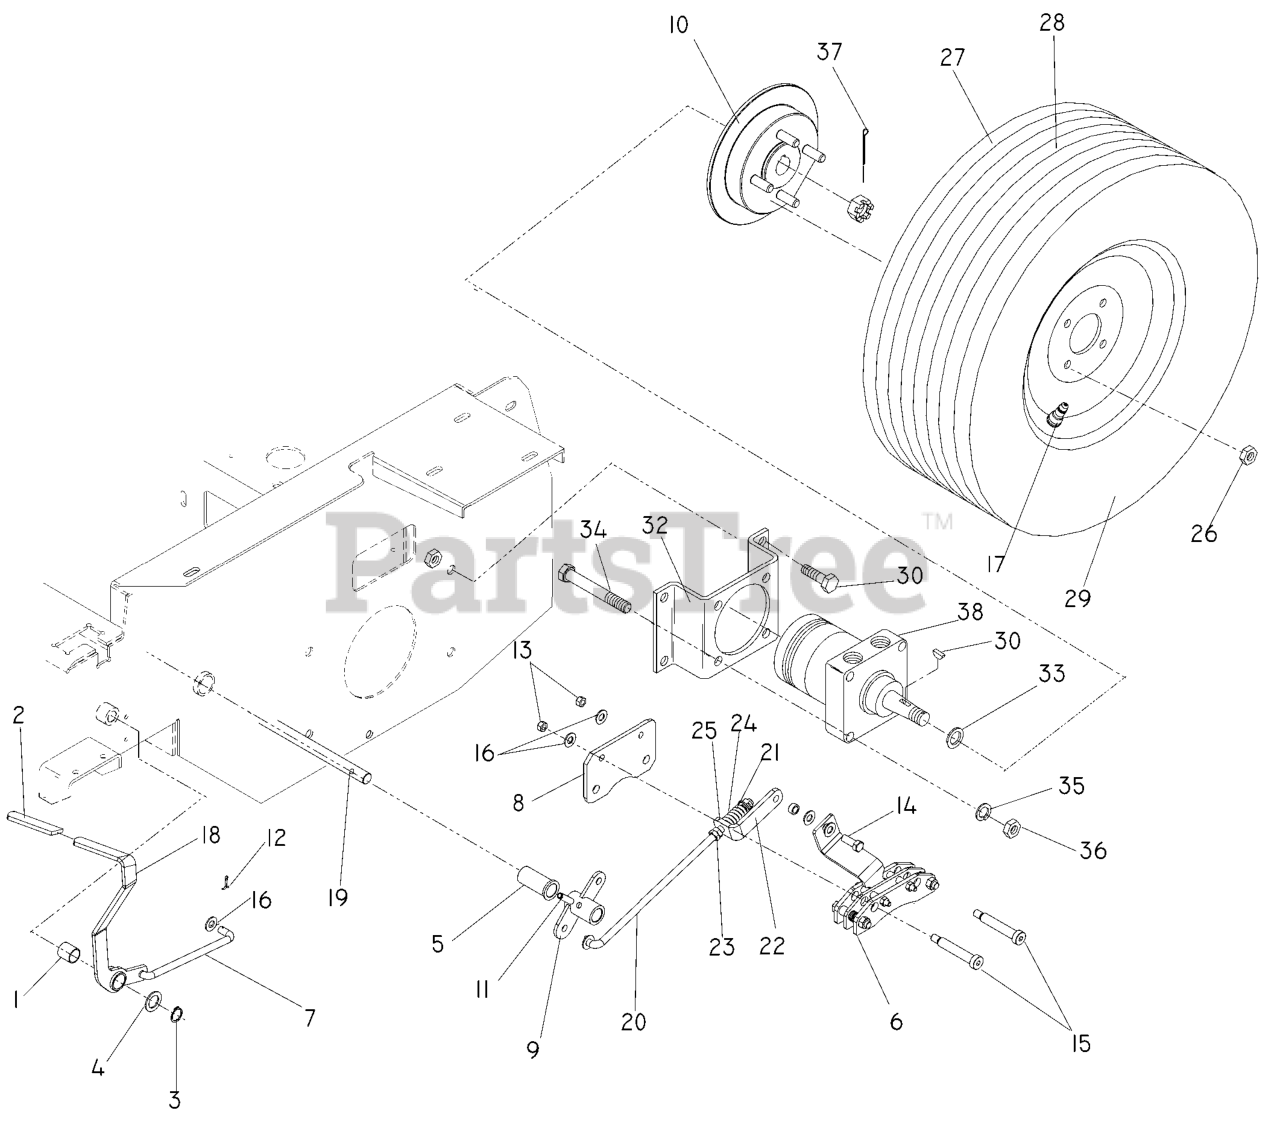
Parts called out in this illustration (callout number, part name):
2	GRIP, PARK BRAKE
3	RETAINING RING, 7/8"
4	BSHG .875 X 1.375 X .074 ZD
5	BUSHING, POLYMER 3/4X2
6	CALIPER ASSEMBLY
7	LINKAGE, BRAKE
8	PLATE, BRAKE
9	BELLCRANK, BRAKE
11	5/16 DIA ROLL PIN
12	COTTER PIN 3/32 X 3/4
13	NUT HEX 3/8-16 NYLON, THIN
14	HCS 3/8-16X1.GRD.5.ZD
15	SB 3/8-16 X 2-1-1/2 SKT HDD ZD
16	WASHER 3/8 SAE FLAT
17	VALVE STEM TR-412
18	BRAKE LEVER WLDMT
20	LINKAGE, REAR BRAKE
21	NUT 3/8F CENTERLOCK
22	BRACKET, L
23	NUT 3/8-24 JAM
24	WASHER 3/8 SAE FLAT
26	LUG NUT 1/2F
27	WHEEL/TIRE.ASM.24X12-12.SILVER
28	TIRE.24X12-12.TURF.MASTER
29	12"RIM 2.5" NEG OFFSET 8.5" W
30	WOODRUFF KEY
31	NUT 1/2-13 HEX NYLOC ZD
32	MOUNT, MOTOR, WHEEL - BLK
33	MACHINE BUSHING
34	HCS 1/2C X 2 3/4
35	WASHER 1/2" SPLIT LOCK
36	NUT HEX 1/2
37	PIN COTTER 4MM X 45MM
38	TL15 WHEEL MOTOR
